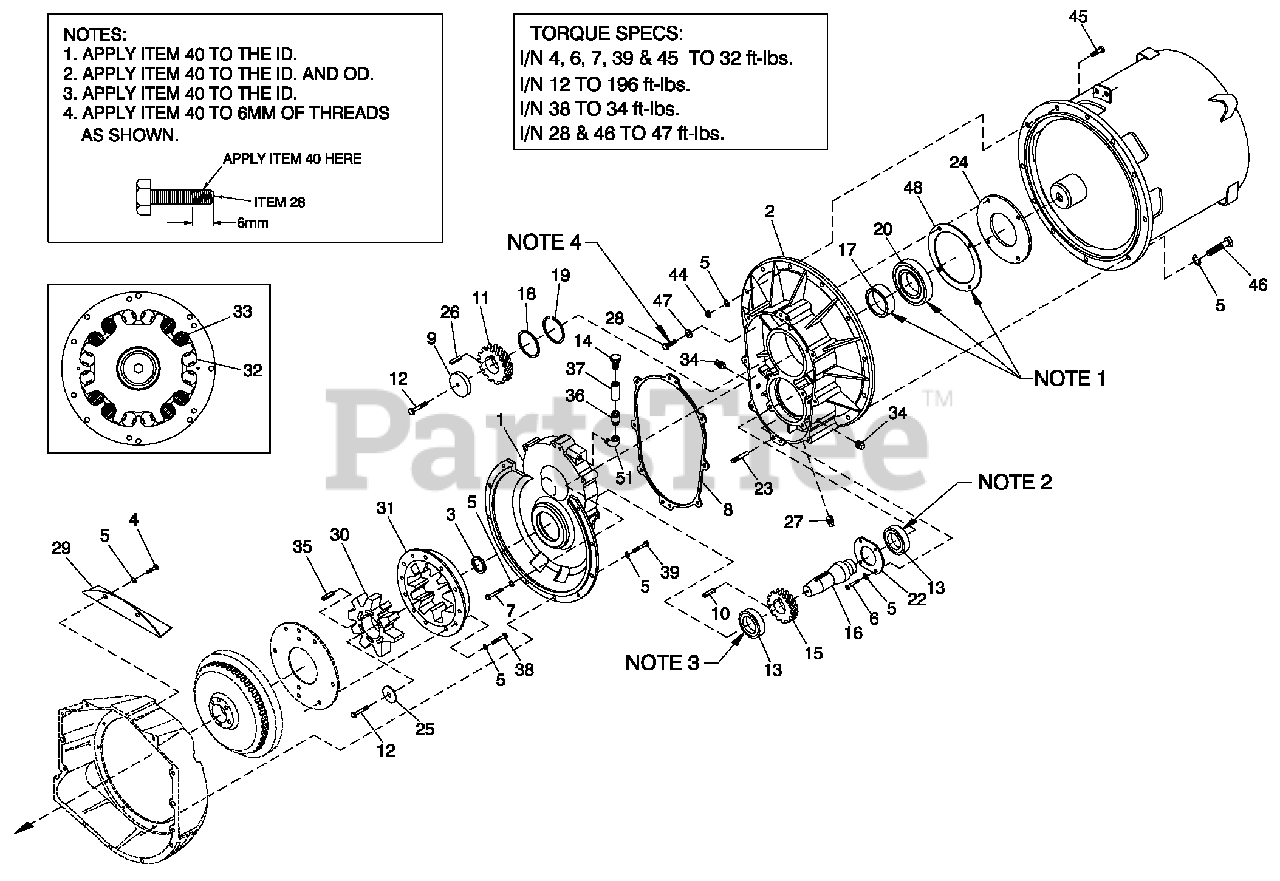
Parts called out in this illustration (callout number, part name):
1	GEAR CASE ENG. MACHINED
2	GEAR CASE ALT. MACHINED
3	SEALOIL
4	S CREW HHC M10l1.5X 20 G8.8
5	WASHER LOCK M10
6	S CREW HHC M10l1.5X 25 G8.8
7	S CREW HHC M10l1.5X 70 G8.8
8	GASKET 390 GEAR BOX
9	S PACER .69 X 2.75 X .37 ST/ZNC
10	KEY 1 0X 1 6 X 4 6
11	GEAR OUTPUT 1.65:1
12	SCREW HHC M16-2.0X 35 G10.9
13	BALLBRG65X 120X23
14	BREATHER
15	GEAR INPUT 1.65:1
16	SHAFT 390 INPUT GEAR
17	COLLAR HARDENED
18	SEALOIL
19	SNAP RING INT120MM
20	BEARING #6213 SEALED
22	PLATE INTRNLBRG RET
23	PIN DOWEL M8X 24
24	PLATE BEARING THRST
25	SPACER STRESSPROOF
26	KEY 1 0X 1 6 X 4 0
27	PLUG PIPE 3/8"MAGNETIC
28	SCREW HHFC M10-1.5X 25 G10.9
29	COVER GEARBOX GUARD
30	COUPLING INNER DRAWN
31	COUPLING OUTER MACHN
32	DAMPER GB CPLRVIBRA
33	DAMPER GB CPLRVIBRA
34	PLUG STD PIPE 3/8 STEEL SQ HD
35	KEY 1 0X 1 6 X 5 0
36	NIPPLE PIPE3/8NPTX 3-1/2
37	COUPLING FULL 3/8-18
38	SCREW HHC 3/8-16 X1-1/2G8
39	SCREW HHC M10-1.5X 25 G8.8
40	RETAINING COMPOUND
44	NUT HEX M10-1.5G8 YELCHR
45	SCREW HHC M10-1.5X 60 G8.8
46	SCREW HHC M10-1.5X 40 G10.9
47	WAS HER FLAT M10 S EALING COPPER
48	GASKET SEAL PLATE 390 G B
50	THREADLOCK AND SEALANT
51	ELB OW 90DSTREET3/8
